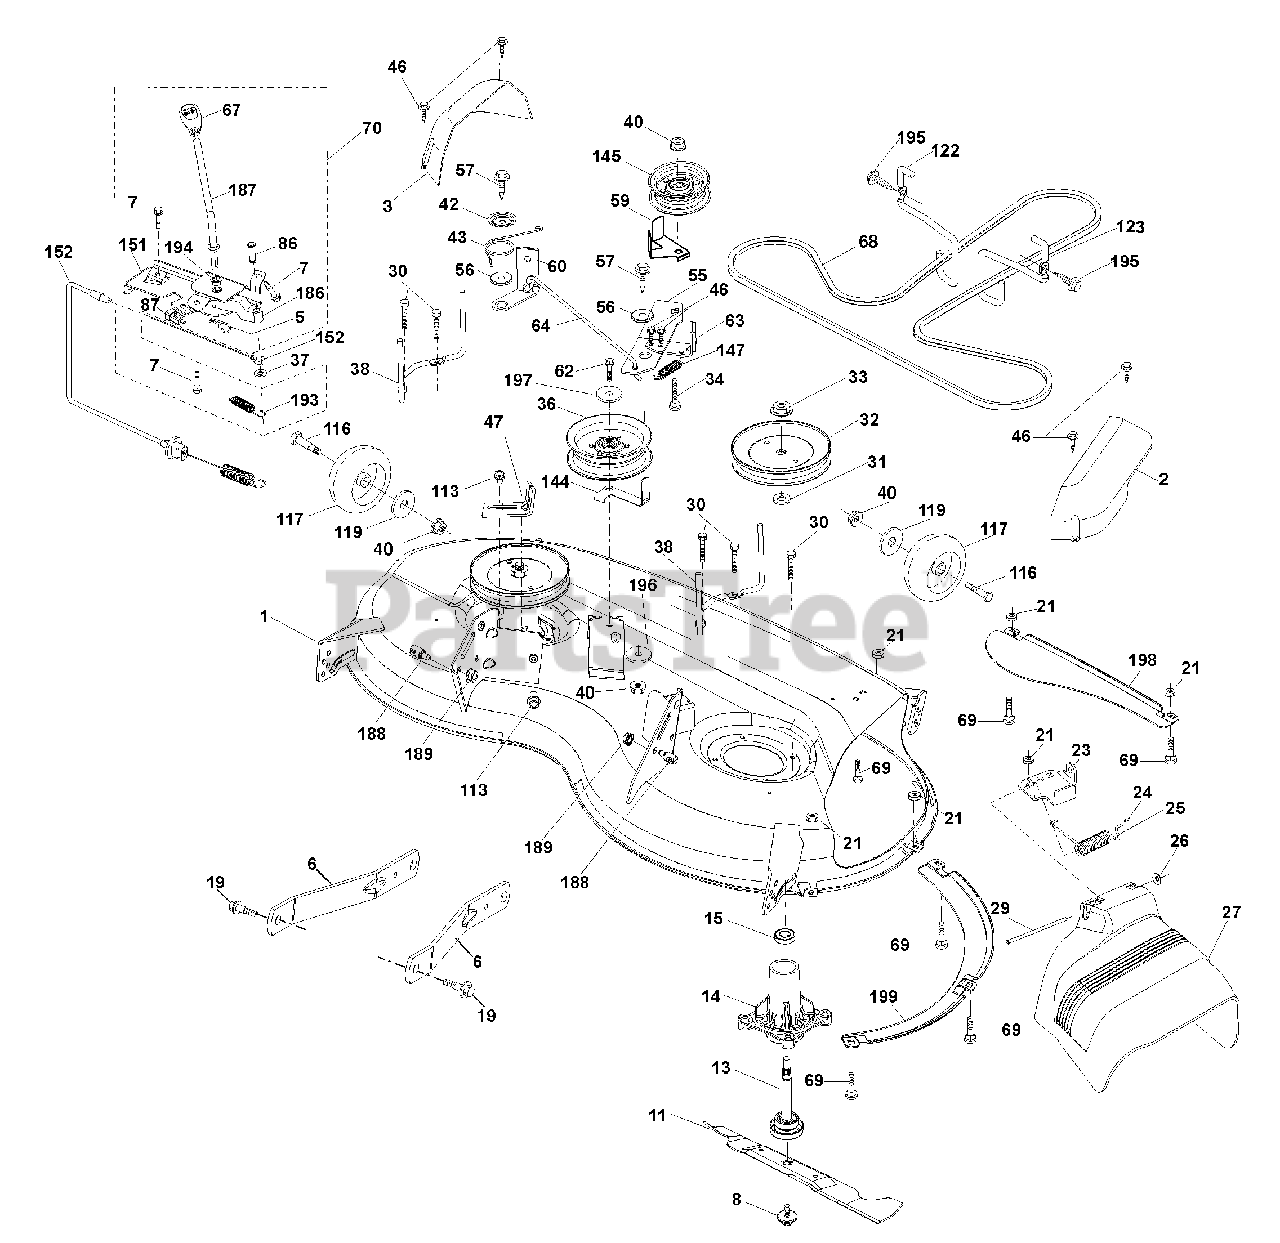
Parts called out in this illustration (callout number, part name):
2	Cover Mandrel RH
3	Cover Mandrel LH
5	Retainer Spring
6	Arm Suspension
7	Screw 10 x 3/4 Single Hex
8	Bolt/Washer asm 7/16-20 unf
11	Blade Mower
13	Shaft Assembly, Mandrel
14	Housing, Mandrel
15	Bearing, Ball, Mandrel
19	Bolt, Shoulder
21	Nut
23	Bracket, Deflector
24	Cap, Sleeve
25	Spring, Torsion, Deflector
26	Nut, Push
27	Shield, Deflector
29	Rod, Hinge
30	Screw Thdrol Rolling Wsh Hd
31	Washer, Spacer
32	Pulley, Mandrel
33	Nut, Toplock, Flanged
34	Bolt Carr Sh. 3/8-16 x 1-1/2 Gr. 5
36	Pulley, Idler, Flat
37	Washer 13/32 x 13/16 x 16 Ga.
38	Keeper Belt LH Mandrel
40	Nut, Lock Flg. 3/8-16 unc
42	Spring Trosion Brake
43	Spring Torsion Retainer
46	Screw
47	Bracket Clutch Cable
55	Arm, Idler
56	Spacer, Retainer
57	Screw Hexwsh Thd 3/8-16 x 1
59	Guard, Tuv Idler (94)
60	Arm Brake Mower
62	Bolt Fin Hex 3/8-16 x 2-1/4 Gr. 5
63	Arm Brake Mower
64	Linkage Brake
67	Handle, Clutch Cable
68	V-Belt
69	Bolt
70	Clutch Asm. Manual
86	Pin Attachment Cable
87	Switch Interlock
113	Screw 5/16-18
116	Bolt, Shoulder
117	Wheel, Gauge
118	Nut, Crownlock 3/8-1
119	Washer 13/32 x 7/8 x 14 Ga.
122	Keeper Belt Eng. LH
123	Keeper Belt Eng. RH
144	Keeper Belt
145	Pulley Idler
147	Spring Return
151	Bracket Clutch CBL
152	Cable Clutch Manual w/Spr.
186	Arm Acutator CL Cable
187	Lever Control CL Cable
188	Stud Fastener
189	Nut Lock Hex Flange
193	Spring Plunger Actuator
194	Bearing Control Lever Clutch
195	Screw 3/8-16 x 3/4
196	Washer 13/32 x 2 x 10 Ga
197	Washer 13/32 x 13/16 x 12 Ga.
198	Baffle Center Front
199	Baffle Front RH
199	Mandrel Assembly
199	Replacement Mower, Complete
